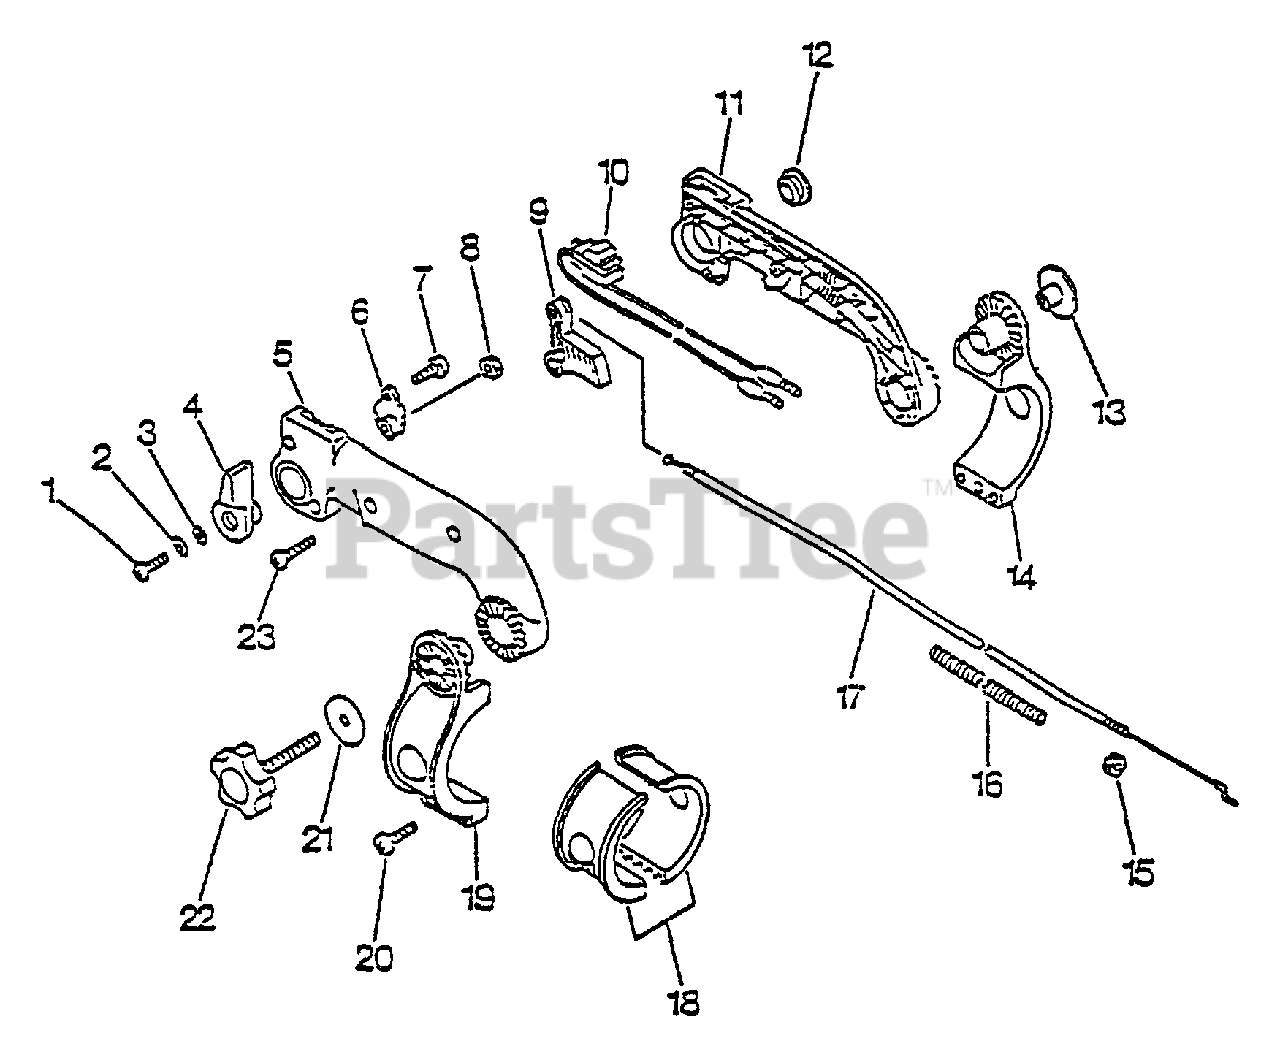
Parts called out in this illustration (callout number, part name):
1	SCREW - 6X20
2	LOCKWASHER - 6
3	WASHER - 6
4	TRIGGER, THROTTLE
5	HANDLE, CONTROL - LEFT
6	BRACKET, THROTTLE
7	SCREW - 4X10
8	LOCKNUT - 6
9	TRIGGER, THROTTLE
10	IGNITION SWITCH ASSY
11	HANDLE, CONTROL - RIGHT
14	BRACKET, HANDLE - RIGHT
15	LOCKNUT - 6
16	TUBE, PROTECTIVE - CORRUGATED
17	CABLE, THROTTLE
19	BRACKET, HANDLE - LEFT
20	SCREW - 5X20 -- TAPPING
21	WASHER - 6
22	THUMBSCREW
23	SCREW - 4X22
